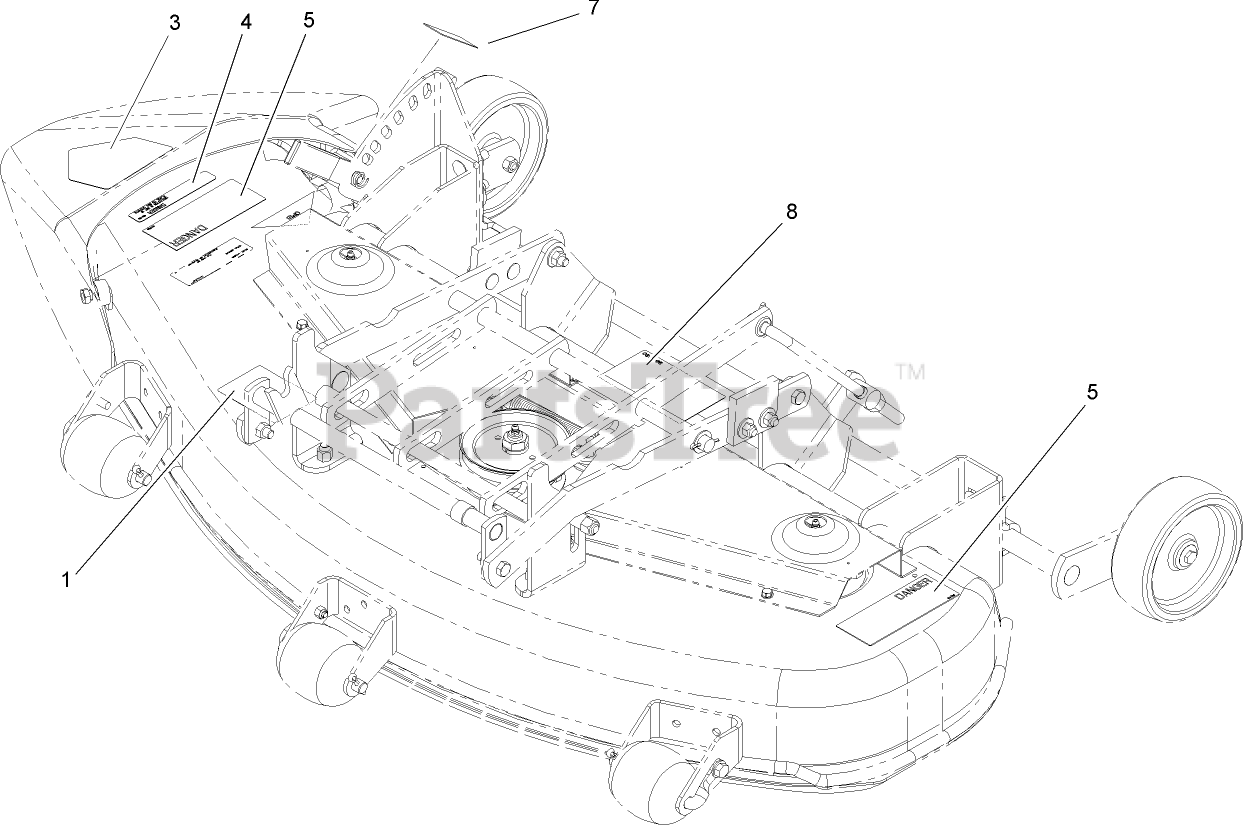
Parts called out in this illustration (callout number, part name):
1	DECAL-BELT ROUTING, PTO
3	DECAL-DANGER
4	DECAL-CAUTION
5	DECAL-DANGER
7	DECAL-HOC
8	DECAL-BELT ROUTING
